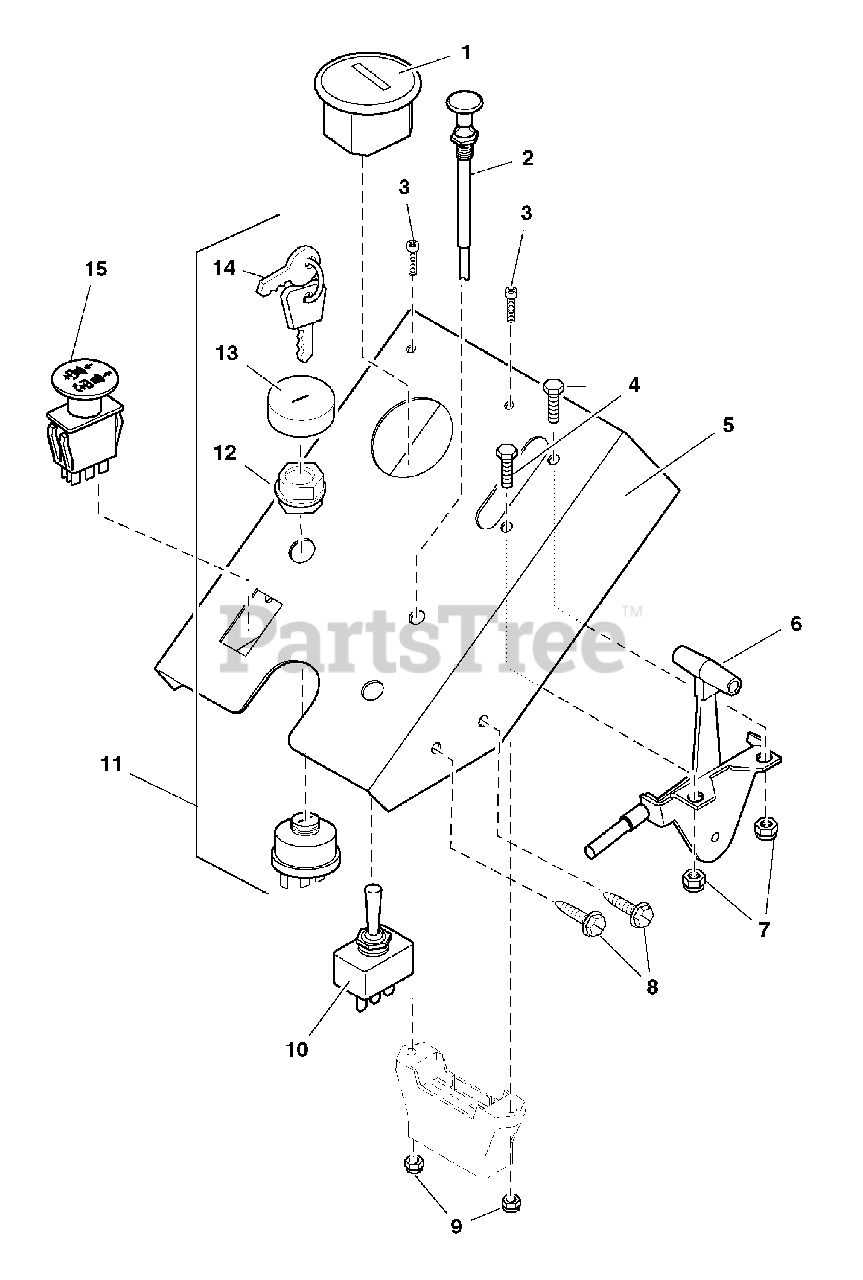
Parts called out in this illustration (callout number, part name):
2	CABLE, Choke Control
3	SCREW, Phillips, #10-24 x 1
4	CAPSCREW, Hex Hd, 1/4-20 x 3/4
6	CABLE, Throttle Control
7	NUT, Hex, Nylon Lock, 1/4-20
8	CAPSCREW, Hex Hd, Self-Tapping, 1/4-20 x 3/4
9	NUT, Hex, Nylon Lock, #10-24
10	SWITCH, Actuator
11	SWITCH, Ignition, complete (includes ref 12-14)
12	PLASTIC NUT
14	KEY, Ignition, Molded (set of 2)
15	SWITCH, PTO
